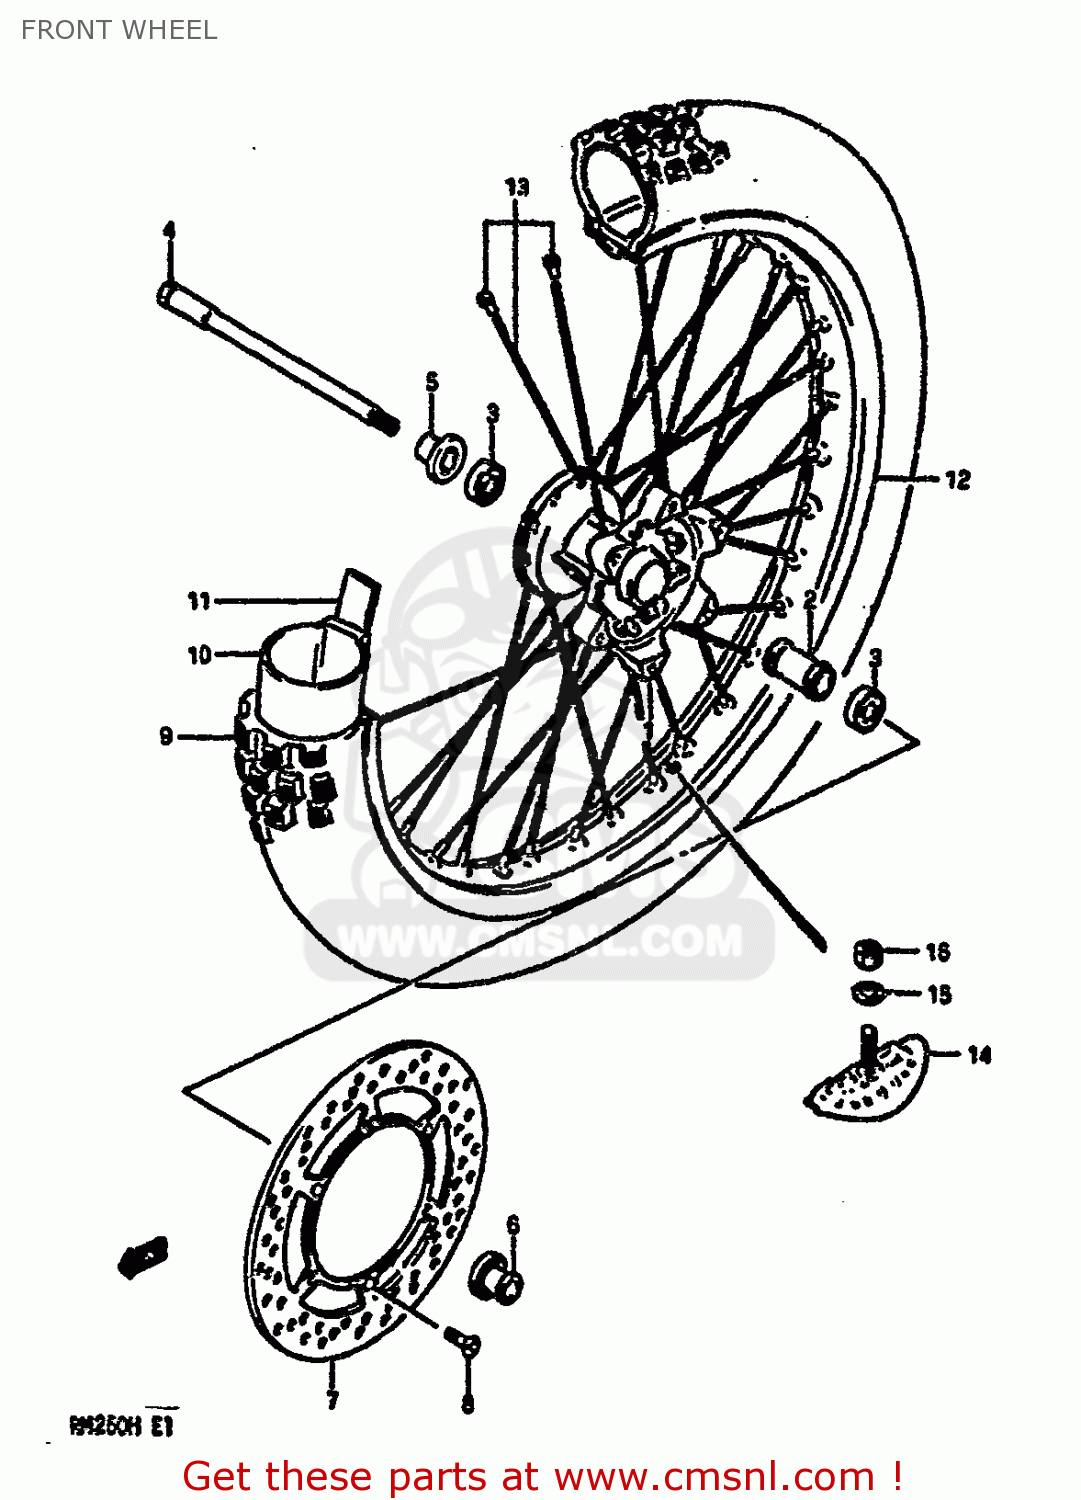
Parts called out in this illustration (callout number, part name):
1	HUB,FRONT
2	SPACER,FR HUB BEARING
3	BEARING
4	AXLE,FRONT
5	SPACER,FRONT AXLE,RIGHT
6	SPACER,FRONT AXLE,LEFT
7	DISC,BRAKE
8	SCREW
9	TIRE,FRONT
10	TUBE
11	PROTECTOR,WHEEL,INNER
12	RIM,FRONT WHEEL
13	SPOKE SET,FRONT
14	STOPPER,BEAD
15	WASHER
16	NUT 8MM
